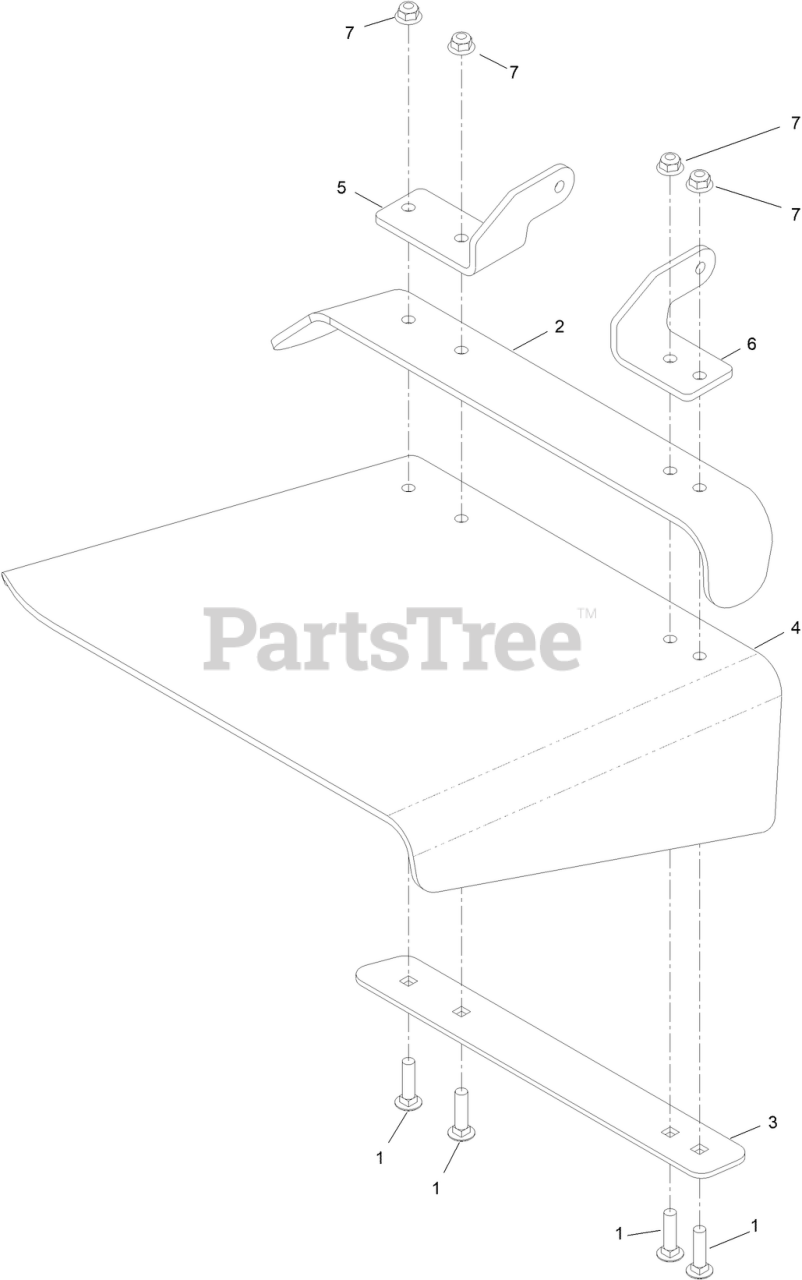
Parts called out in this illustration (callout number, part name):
1	SCREW-CARR
2	DEFLECTOR
3	STRAP-DISCHARGE
4	DEFLECTOR-DECK, RUBBER
5	PLATE-HINGE, REAR
6	PLATE-HINGE, FRONT
7	NUT-HF, NI
